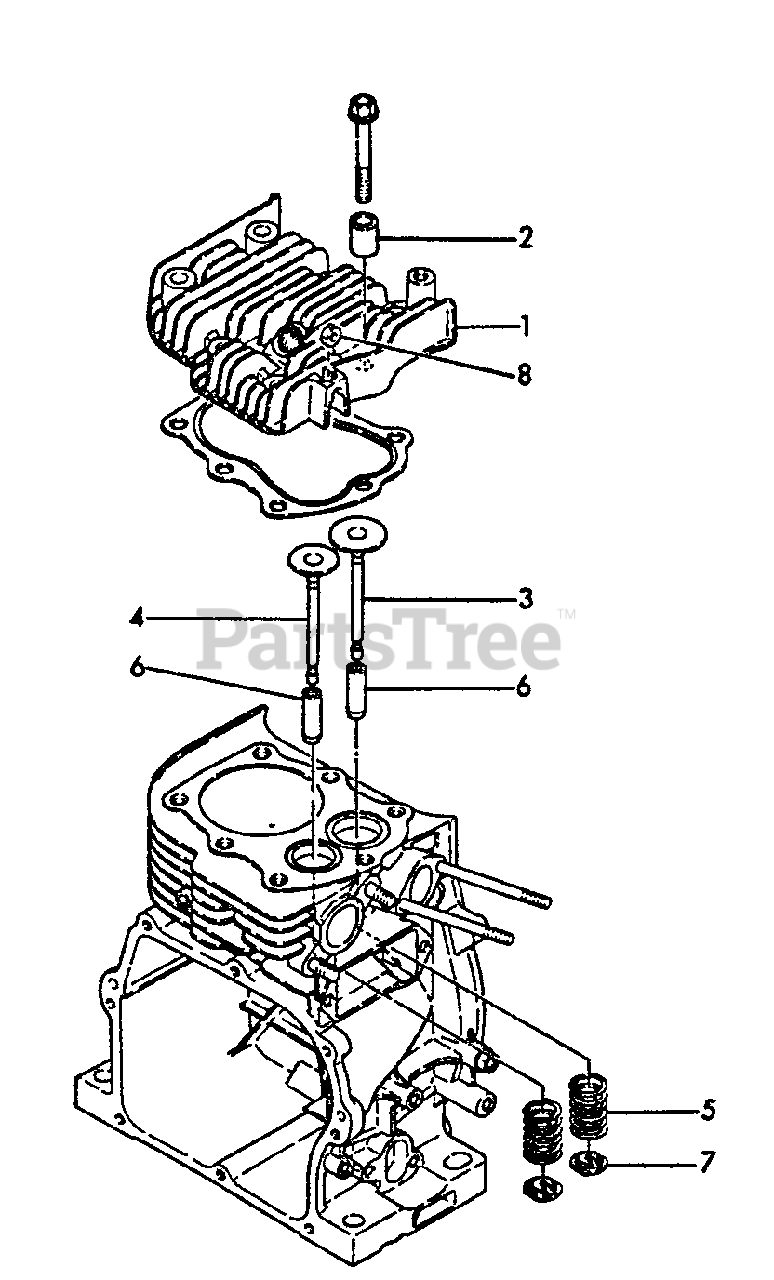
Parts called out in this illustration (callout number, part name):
1	HEAD, CYLINDER
2	SPACER
3	VALVE, INTAKE
4	VALVE, EXHAUST
5	SPRING, VALVE
6	GUIDE, VALVE - EXHAUST
7	RETAINER, SPRING
8	LOCKNUT - 6 -- PLATED
